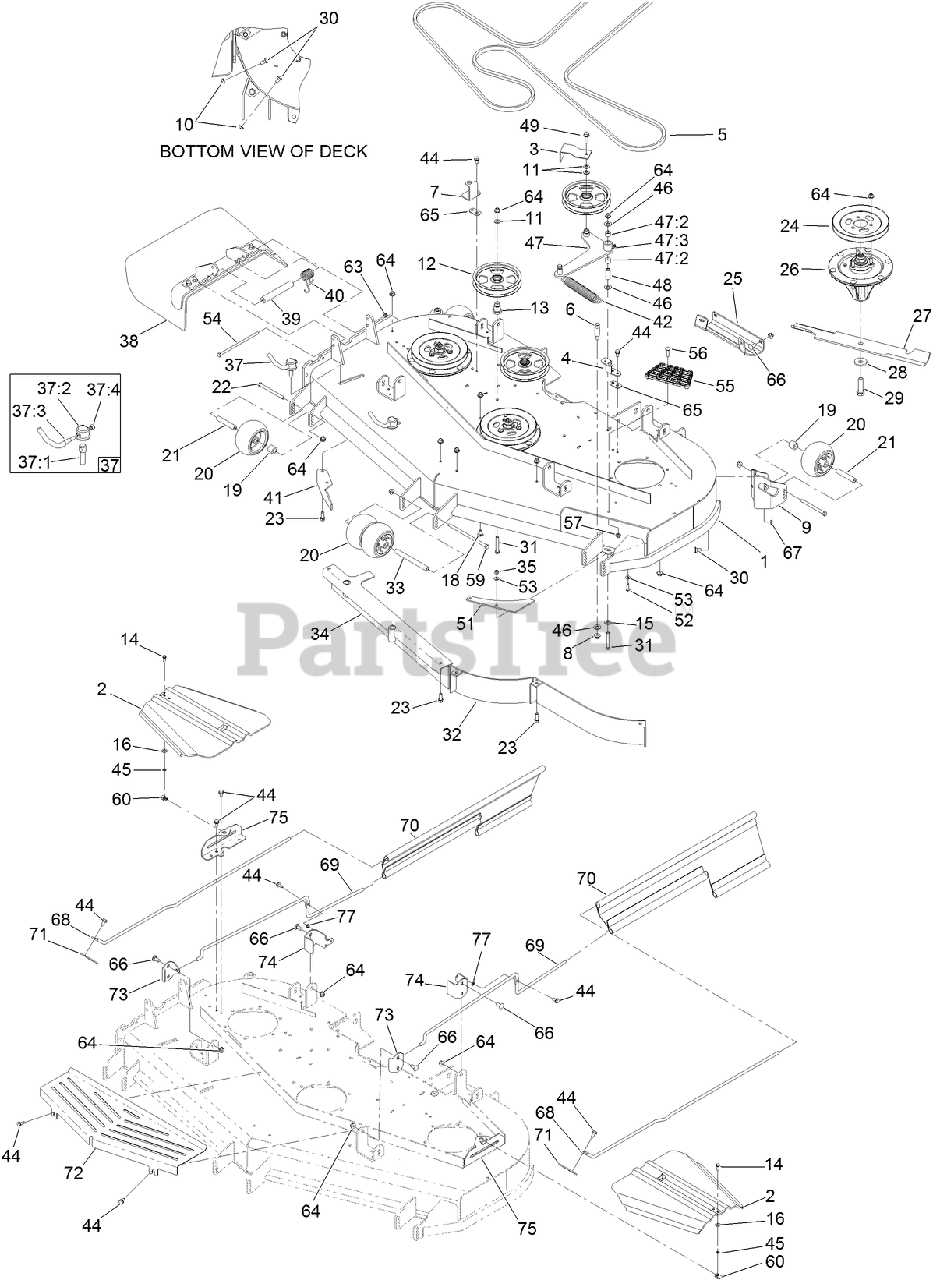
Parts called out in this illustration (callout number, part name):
1	DECK DECAL ASM
2	COVER-BELT
3	GUIDE-BELT
4	BRACKET-COVER, TALL
5	BELT-V
6	PIN-THREADED, SPRING ANCHOR
7	BRACKET-COVER
8	NUT-HF
9	MOUNT-WHEEL, LH
10	NUT-HHF, WHIZ
11	WASHER-FLAT
12	PULLEY-IDLER, FLAT
13	MOUNT-PULLEY
14	SCREW-HWH
15	WASHER-BELLEVILLE
16	WASHER-THRUST
18	SCREW-CARR
19	TUBE-SPACER
20	ROLLER-SCALP, ANTI
21	TUBE-SPANNER
22	SCREW-HH
24	PULLEY
25	PLATE-SKID
26	SPINDLE ASM
27	BLADE-HI FLOW
28	WASHER-BLADE BOLT, HEAVY
29	SCREW-BLADE
30	SCREW-HH
31	SCREW-HH
33	SPACER-WHEEL
34	BAFFLE ASM
35	NUT-LOCK, NI
37	LEVER ASM
37:1	SCREW-LOCK
37:2	CAP-LOCK
37:4	NUT-LOCK, NI
38	RUBBER DEFLECTOR ASM
39	SPACER
40	SPRING-TORSION
41	BAFFLE-DISCHARGE
42	SPRING-EXTENSION
44	SCREW-HWHTF
45	NUT-RETAINER
46	WASHER-FLAT
47	DECK IDLER ARM ASM
47:2	SLEEVE-BEARING
47:3	FITTING-GREASE, 90 DEG
48	BUSHING
49	SCREW-HHF
51	PLATE-TURBO
52	SCREW-HSBH
53	WASHER-SPRING
54	SCREW-HH
55	STEP-DECK
56	SCREW-CARR
57	NUT-HF, NI
59	SCREW-HH
63	NUT-LOCK, NI
64	NUT-HF, NI
65	SPACER-BELT COVER
66	SCREW-CARR
68	ROD-SUPPORT, UPPER
69	ROD-SUPPORT, LOWER
70	GUARD-SIDE
71	BRACKET-MOUNTING, UPPER ROD
72	SHIELD-FRONT, DECK
73	BRACKET-MOUNTING, FRONT
74	BRACKET-MOUNTING, REAR
75	BRACKET-SUPPORT, SPINDLE COVER
77	NUT-PUSH
